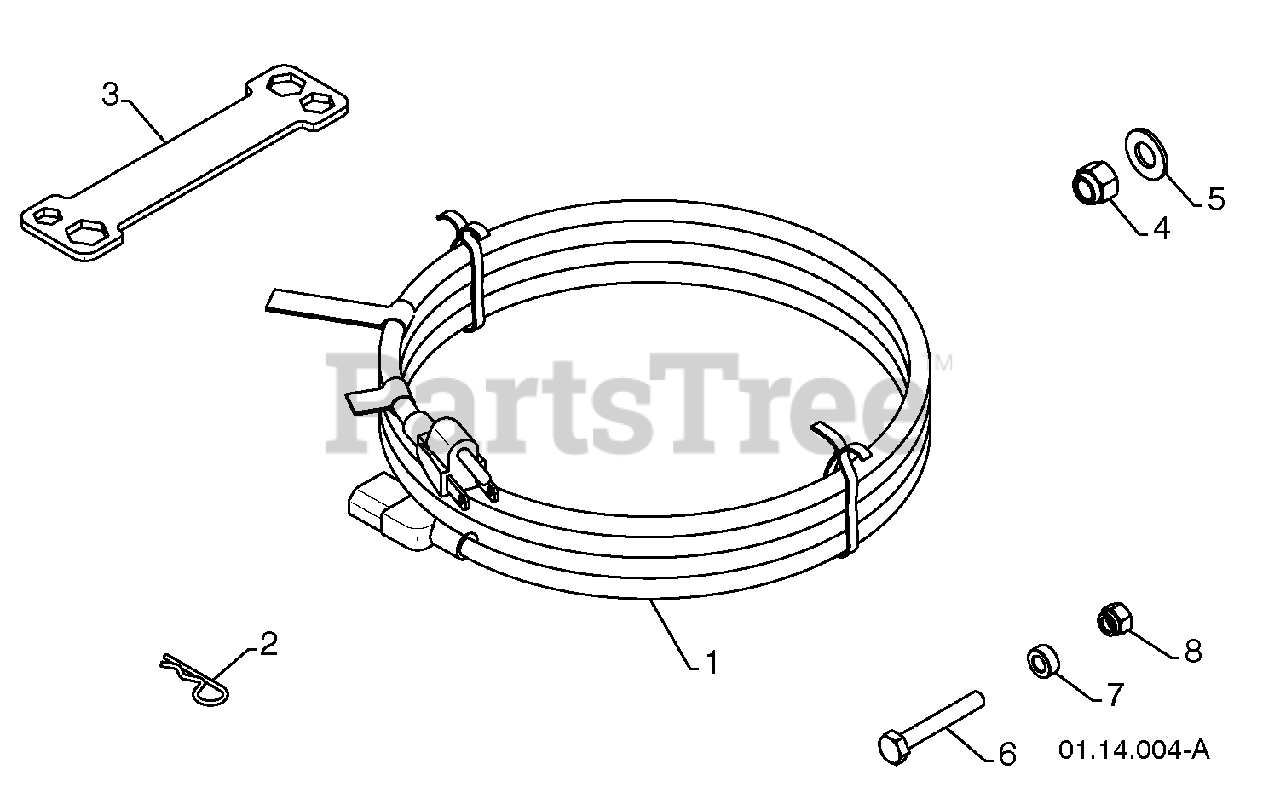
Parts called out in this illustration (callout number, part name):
1	POWER CORD
2	RETAINER PIN
3	WRENCH
4	LOCKNUT 3/8-16
5	WASHER 3/8
6	SHEAR BOLT 1/4-20 X 1-3/4
7	SPACER
8	LOCKNUT 1/4-20
